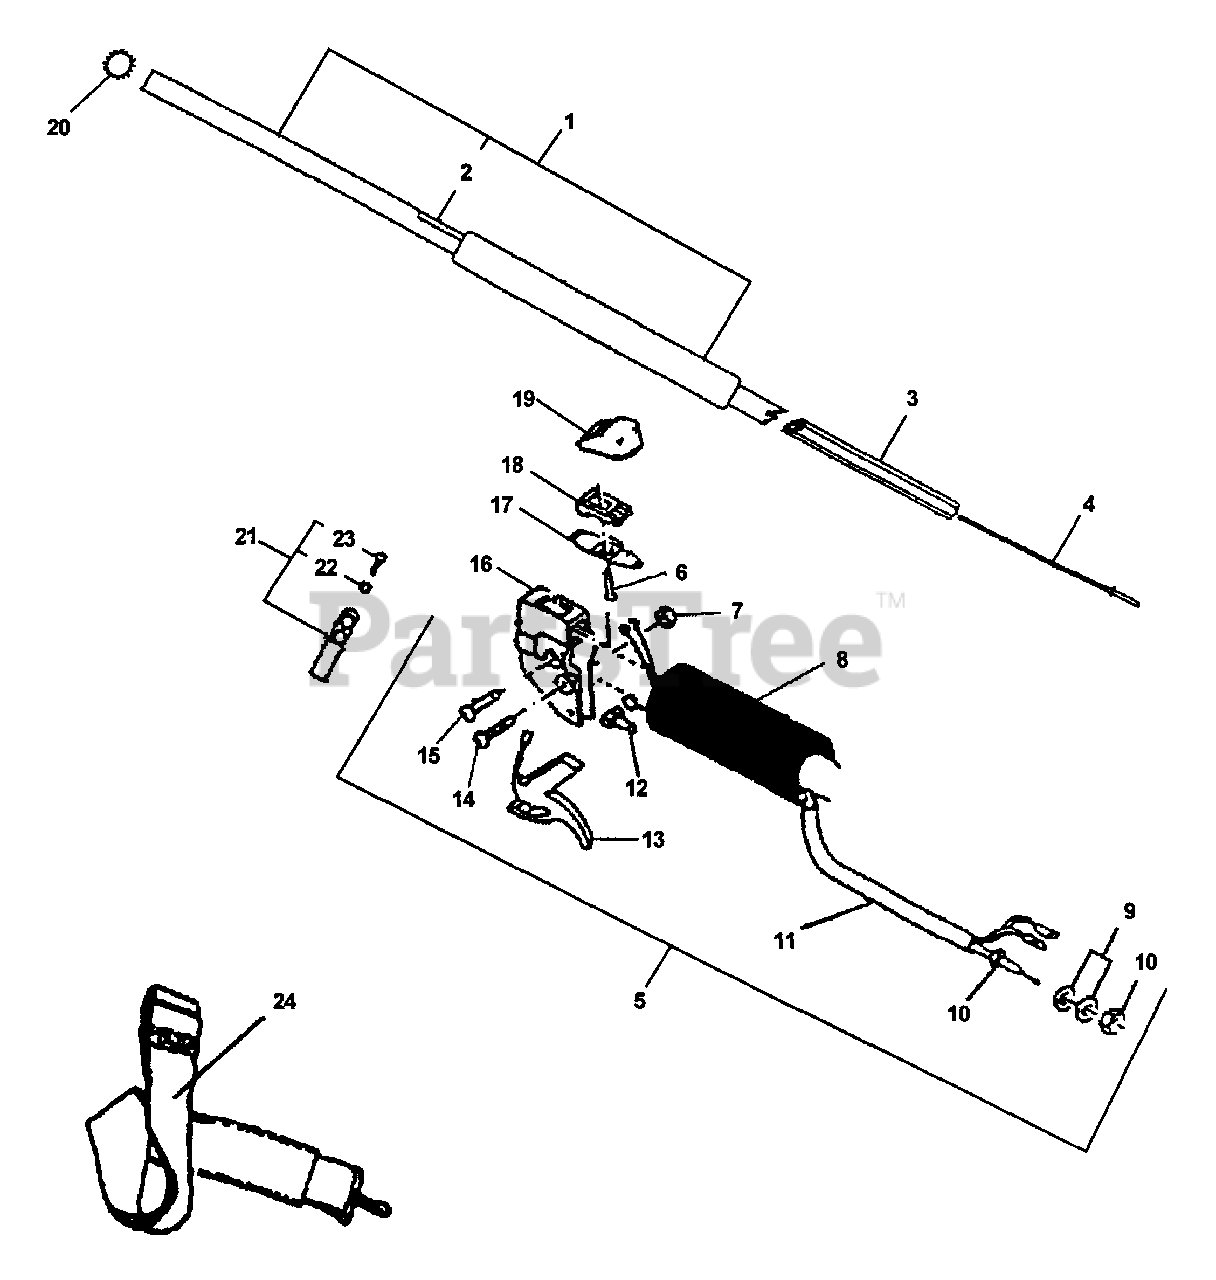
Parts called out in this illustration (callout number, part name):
1	MAIN PIPE ASSY
2	LABEL - WARNING
3	LINER - FLEXIBLE
4	DRIVESHAFT - FLEXIBLE
5	THROTTLE CONTROL ASSY
6	SCREW
7	NUT - 5
8	GRIP, HANDLE
9	WASHER - 6
10	NUT - 6
11	CONTROL CABLE ASSY
12	GUIDE, CABLE
13	TRIGGER, THROTTLE
14	SCREW - 5
15	SCREW
16	BRACKET, THROTTLE CONTROL
17	TERMINAL - GROUND
18	IGNITION SWITCH ASSY
19	KNOB, SWITCH
20	LOCKWASHER - EXTERNAL
21	HANGER KIT
22	LOCKNUT - 10-24
23	SCREW
24	SHOULDER STRAP ASSY
